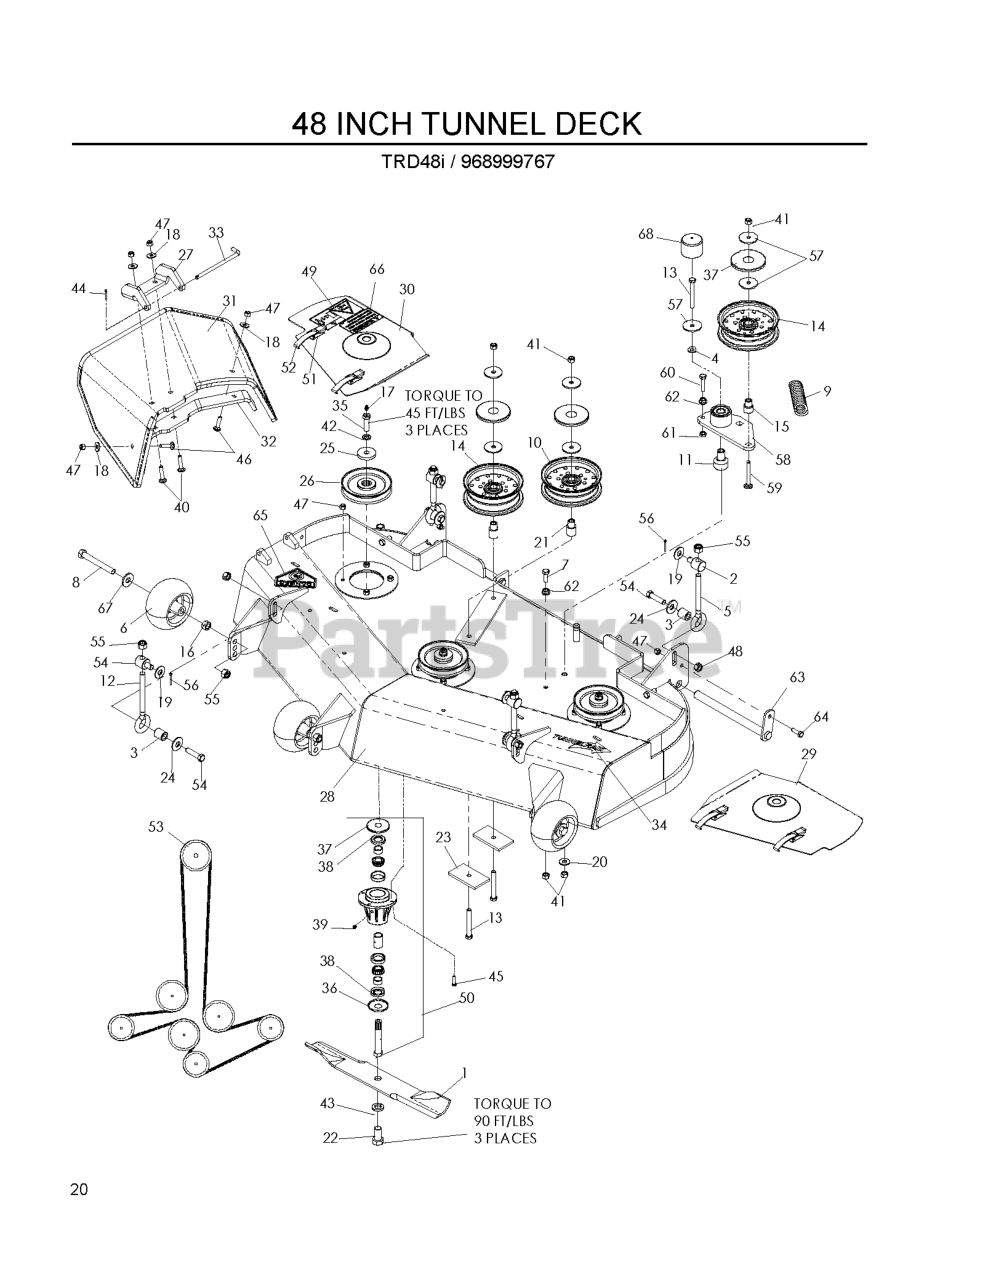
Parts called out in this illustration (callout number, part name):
1	BLADE OEM 16 1/4"
4	WASHER 3/8 SAE FLAT
6	GAUGE WHEEL
7	HCS 3/8-16X1.GRD.5.ZD
8	HHB, 1/2-13X4
10	IDLER PULLEY (TALL)
11	PIVOT, BEARING
12	EYEBOLT, 1/2-13 X 5.88
13	HCS 3/8C X 3
14	IDLER PULLEY
15	BUSHING, IDLER
16	NUT HEX 1/2
17	ZERK
18	WASHER 5/16 FLAT
19	WASHER 1/2 FLAT
20	WASHER 3/8 FLAT
21	IDLER BUSHING
22	HCS 5/8F X 1 1/4
23	SUPPORT PLATE
24	SPRING WASHER - .50
25	SPINDLE WASHER
26	PULLEY 42-48
27	PIVOT BRACKET - RUBBER CHUTE
28	DECK W/DECALS 48" HUS
29	48 BELT SHIELD ASM - RH
30	48 BELT SHIELD ASM - LH
31	CHUTE, RUBBER DISCHARGE 42/48"
32	BRACKET, REINF-CHUTE
33	PIN, CHUTE PIVOT
34	DECAL, TUNNEL RAM 6"
35	HCS 7/16-20 GD 8 SPEC
36	BOTTOM DUST CAP
37	TOP DUST CAP
38	SHAFT SEAL
39	PLUG-VENTED
40	RHSNB 5/16-18 X 1-1/2 GR 5 ZD
41	NUT 3/8-16 NYLOC
42	WASHER 7/16 LOCK
43	LOCKWASHER 5/8
44	RP_COTTER PIN 1/8 X 3/4
45	HCS 5/16C X 1 1/4
46	BOLT, CARRIAGE 5/16X1-1/4
47	NUT 5/16 NYLOC
48	NUT 7/16C CENTERLOCK
49	DECAL, EURO SEVERING
50	HOUSING ASM, 52/61
51	RIVET, BLIND, 5/32 DIA
52	DRAW LATCH
53	BELT, DECK 48"
54	HCS 7/16 - 14 X 1 3/4
55	NUT 1/2-13 HEX NYLOC ZD
56	PIN COTTER 1/8 X 1 ZD
57	WASHER, 3/8 SPEC
58	ARM-IDLER W/BRG
59	RHSNB 3/8-16 X 2.75
60	HCS 3/8-16 X 1-1/2
61	NUT 3/8-16 HEX JAM
62	NUT 3/8C WHIZ
64	HCS 5/16C X 1
65	DECAL, CPSC
66	DECAL, CAUTION
67	WASH USS FLAT 1/2
68	CAP, VINYL
